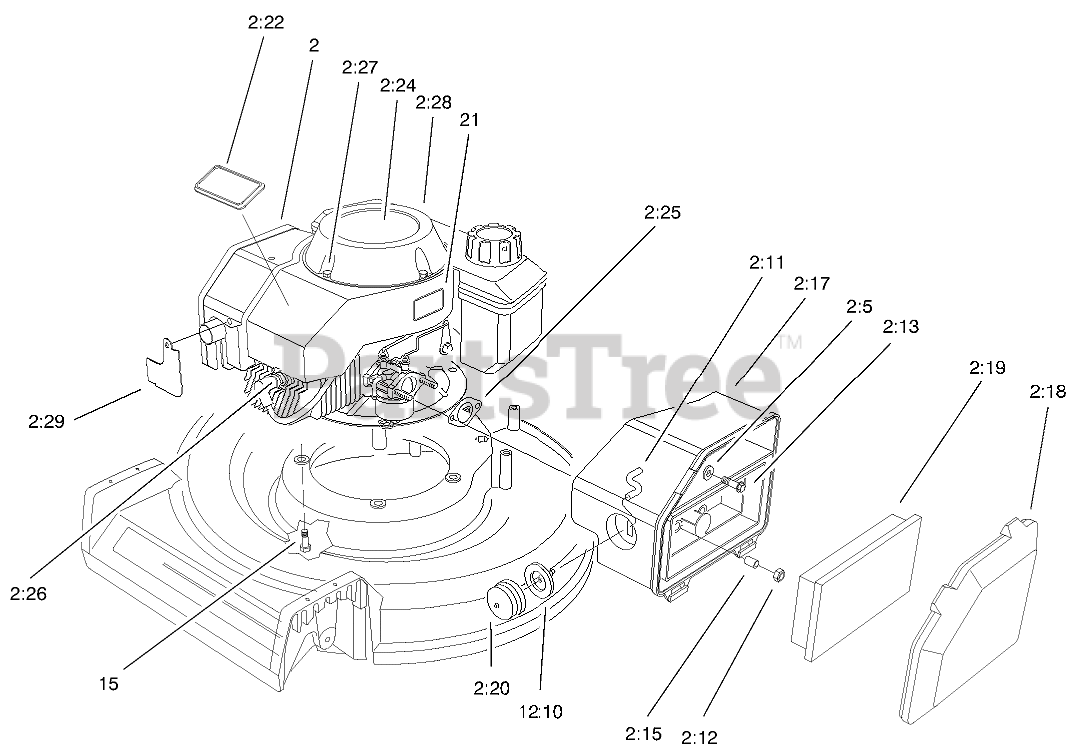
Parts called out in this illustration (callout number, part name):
2	ENGINE ASM - BBC 2 CYCLE
2:5	WASHER-FLAT
2:10	BODY-PRIMER
2:11	HOSE-PRIMER
2:13	SCREW-HH
2:15	SPACER
2:17	BODY-AIR CLEANER
2:18	COVER-AIR CLEANER
2:19	ELEMENT-AIR CLEANER
2:20	BULB-PRIMER
2:22	DECAL - PROLINE
2:24	DECAL-2 CYC RECOIL COMM
2:25	GASKET-AIR CLEANER
2:26	Sparkplug
2:27	SCREW-HHF
2:28	STARTER ASM
2:29	EXTENSION-MUFFLER GUARD
15	SCREW-HHF
21	DECAL-FUEL, 2 CYCLE
